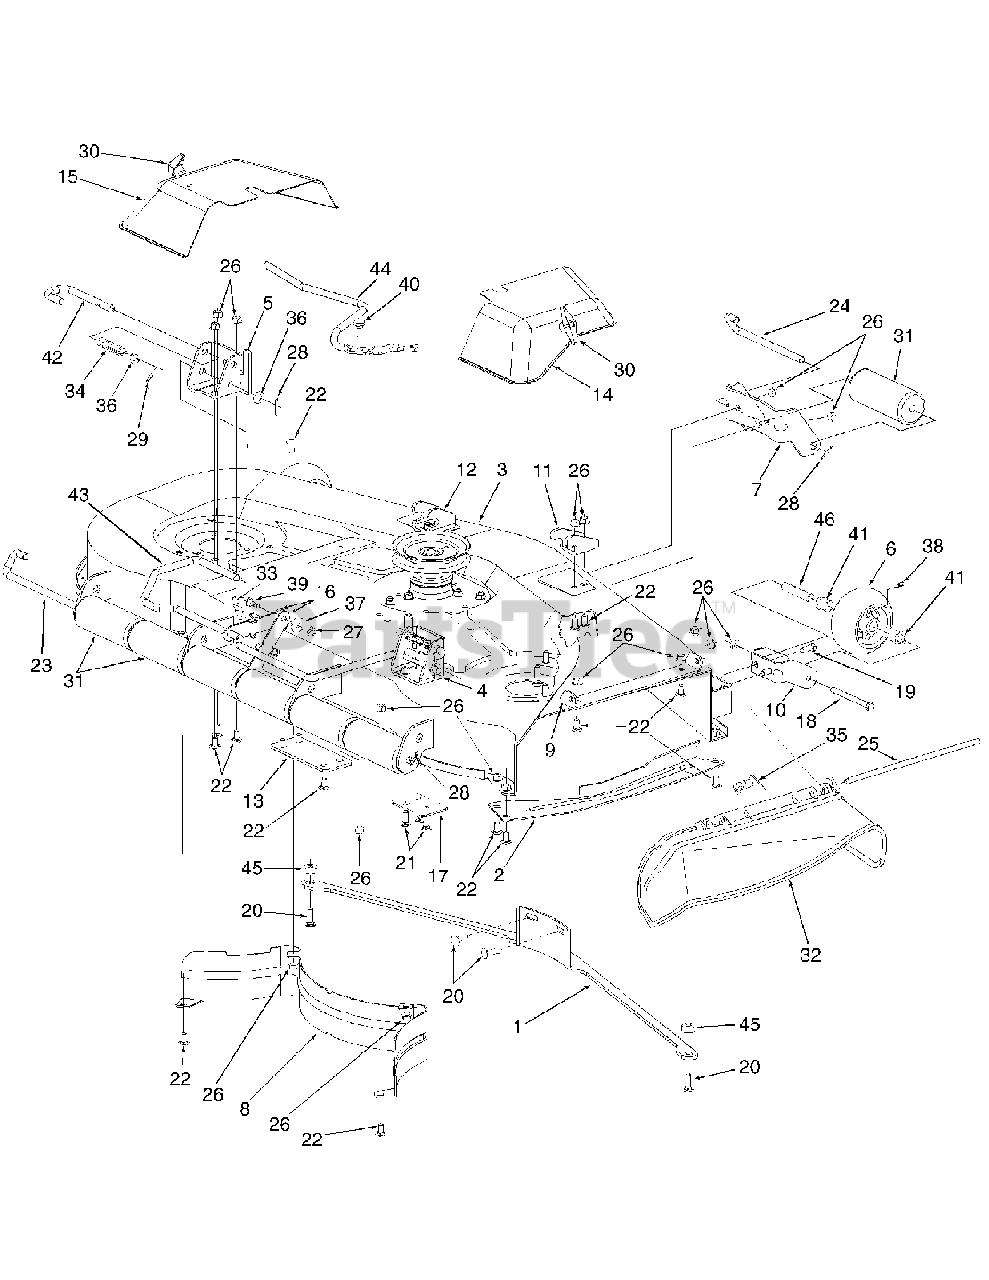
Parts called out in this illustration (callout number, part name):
3	Housing Ass'y, 54" Mower Deck
3	Label, Danger, Top Rt. of Deck
3	Label, Deck Safety, Top Lt. of Deck
4	Bracket, Rear Hanger RH
5	Bracket, Rear Hanger LH
6	Wheel Ass'y, 5" Deck [Includes Ref. Nos. 38 & 41 (Qty. 2)]
7	Bracket, Front Roller
10	Bracket, Deck Wheel
11	Bracket, Front Deck - RH
12	Bracket, Front Deck - LH
15	Cover, Belt - LH
15	Label, Belt Install. - Under Cover
16	Link, Deck Support
19	Screw, Hex Cap, 3/8-16 x .88 GR5
20	Bolt, Carriage, 3/8-16 x 1.25 GR5
21	Bolt, Carriage, 3/8-16 x 1.0 GR5
22	Bolt, Carriage, 3/8-16 x .75 GR5
24	Pin, Roller, 1/2 x 7.31
26	Nut, Hex Flange Lock, 3/8-16
27	Nut, Hex Flange Lock, 5/16-18
28	Pin, Cotter 1/8 x 1.0
29	Pin, Spirol Spring, 3/16 x 3/4
30	Knob, Wingnut, 5/16-18
31	Roller, Front & Rear
32	Deflector, Plastic Chute
32	Label, Danger Cut Finger
33	Spring, Extension
34	Spring, Compression
35	Spring, Torsion
36	Washer, Flat, .536 x .93 x .05
37	Washer, Flat, .344 x 1.125 x .12
38	Grease Fitting
39	Bolt, Shoulder, .437 x .268:5/16-18
40	Bolt, Shoulder, .50 x .267:3/8-16
41	Bearing, Flange
42	Pin, Mower Support
43	Rod, Deck Support
44	Rod, Idler Spring Mtg
45	Spacer, .406 x 1.0 x .38
46	Spacer, Wheel
